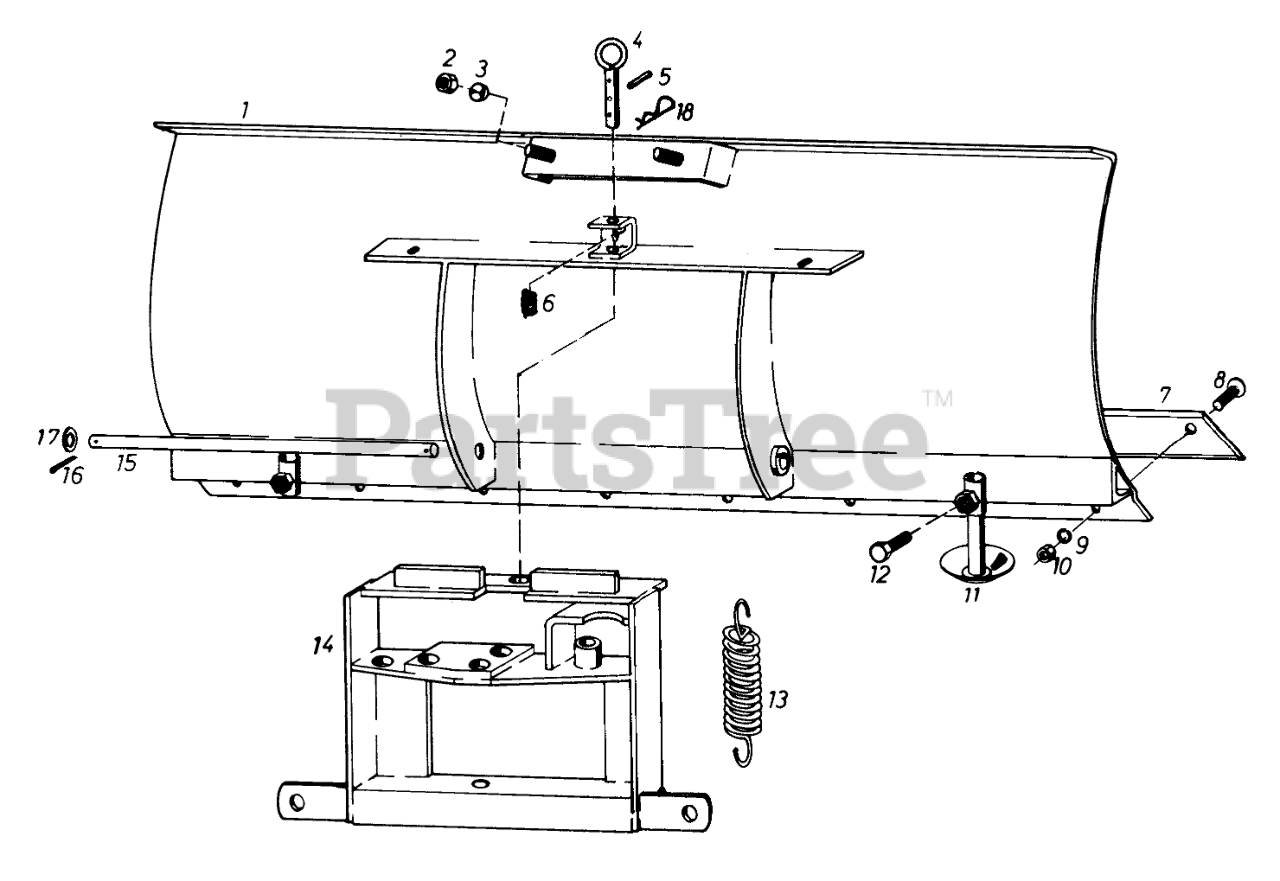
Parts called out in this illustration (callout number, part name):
1	Blade
3	Spring Lockasher
4	Trip Spring Lockout Pin
5	Rollpin
6	Spring
7	Scraper Blade
9	Lockwasher
13	Trip Spring
14	Indexing Bracket
15	Mounting Rod
17	Washer
